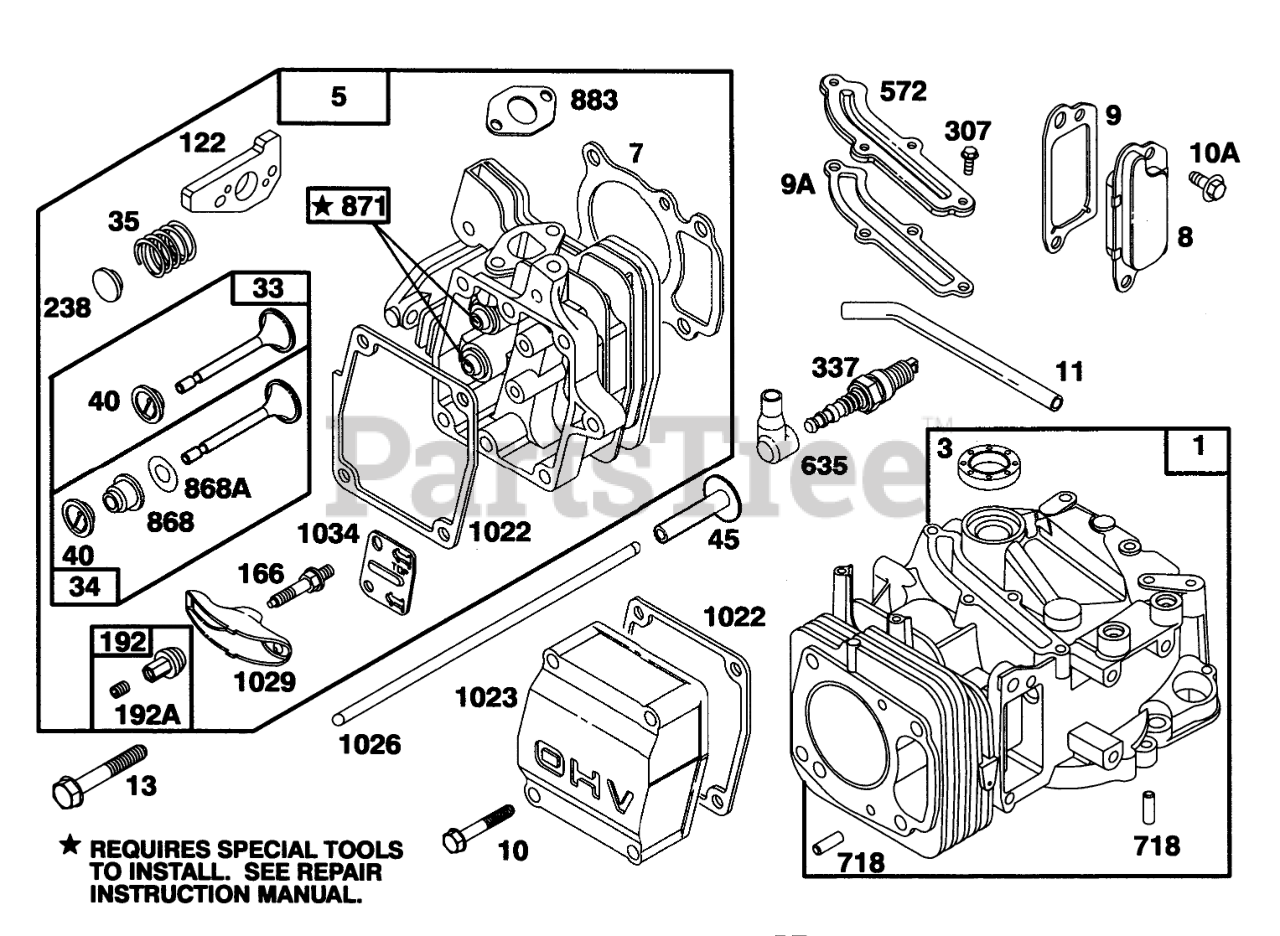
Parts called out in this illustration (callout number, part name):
1	CYLINDER ASSEMBLY
3	SEAL - OIL
5	CYLINDER HEAD
7	CYLINDER HEAD GASKET
8	BREATHER ASM
9	BREATHER GASKET
9A	GASKET-BREATHER
10	HEX HEAD SCREW
10A	HEX HEAD SCREW
11	BREATHER TUBE
13	CYLINDER HEAD SCREW
33	EXHAUST VALVE
34	INTAKE VALVE
35	VALVE SPRING
40	SPRING RETAINER
45	VALVE TAPPET
122	ADAPTER ASSEMBLY
166	ROCKER ARM STUD
192	NUT - HEX SPECIAL
192A	Screw-Set
238	VALVE CAP
307	SCREW - SEM
337	PLUG-SPARK
572	BAFFLE - CYCLINDER
635	SPARK PLUG ELBOW
718	DOWEL - SLEEVE
868	SealAssy-Valve
868A	Seal-Valve
871	Bushing-Guide
883	EXHAUST GASKET
1022	ROCKER COVER GASKET
1023	Cover-Valve
1026	PUSH ROD
1029	ROCKER ARM
1034	PUSH ROD GUIDE
